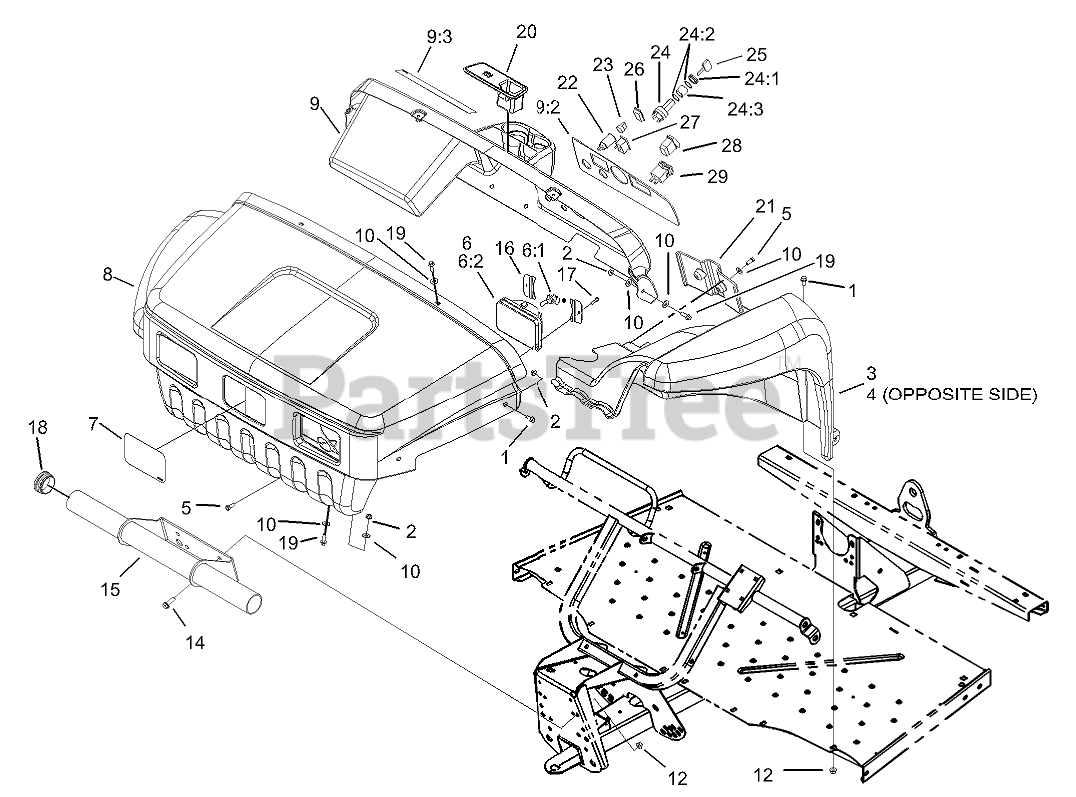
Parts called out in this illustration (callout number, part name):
1	SCREW-HHF
2	NUT-HF, NI
3	LH FENDER ASM
4	RH FENDER ASM
5	SCREW-HHF
6	HEADLIGHT
6:1	LAMP-12 VOLT
6:2	LENS-HEADLIGHT
7	DECAL
8	HOOD ASM
9	DASH ASM
9:2	DECAL-WARNING, DASH
9:3	DECAL-DANGER
10	WASHER-FLAT
12	NUT-HF, NI
15	BUMPER-TUBE
16	BRACKET-HEADLIGHT
17	SCREW-HWH
18	CAP-END
19	SCREW-HHF
20	PLUG-RUBBER
21	COVER-CHANNEL
22	POINT-POWER
24	Switch-Ignition
24:1	NUT-SWITCH, PLASTIC
24:2	WASHER-LOCK, INTERNAL
24:3	SPACER-SWITCH
25	KEY-IGNITION
26	PLUG-HOLE
27	INDICATOR-LIGHT, LOW-OIL PRESSURE
28	SWITCH
29	HOURMETER
